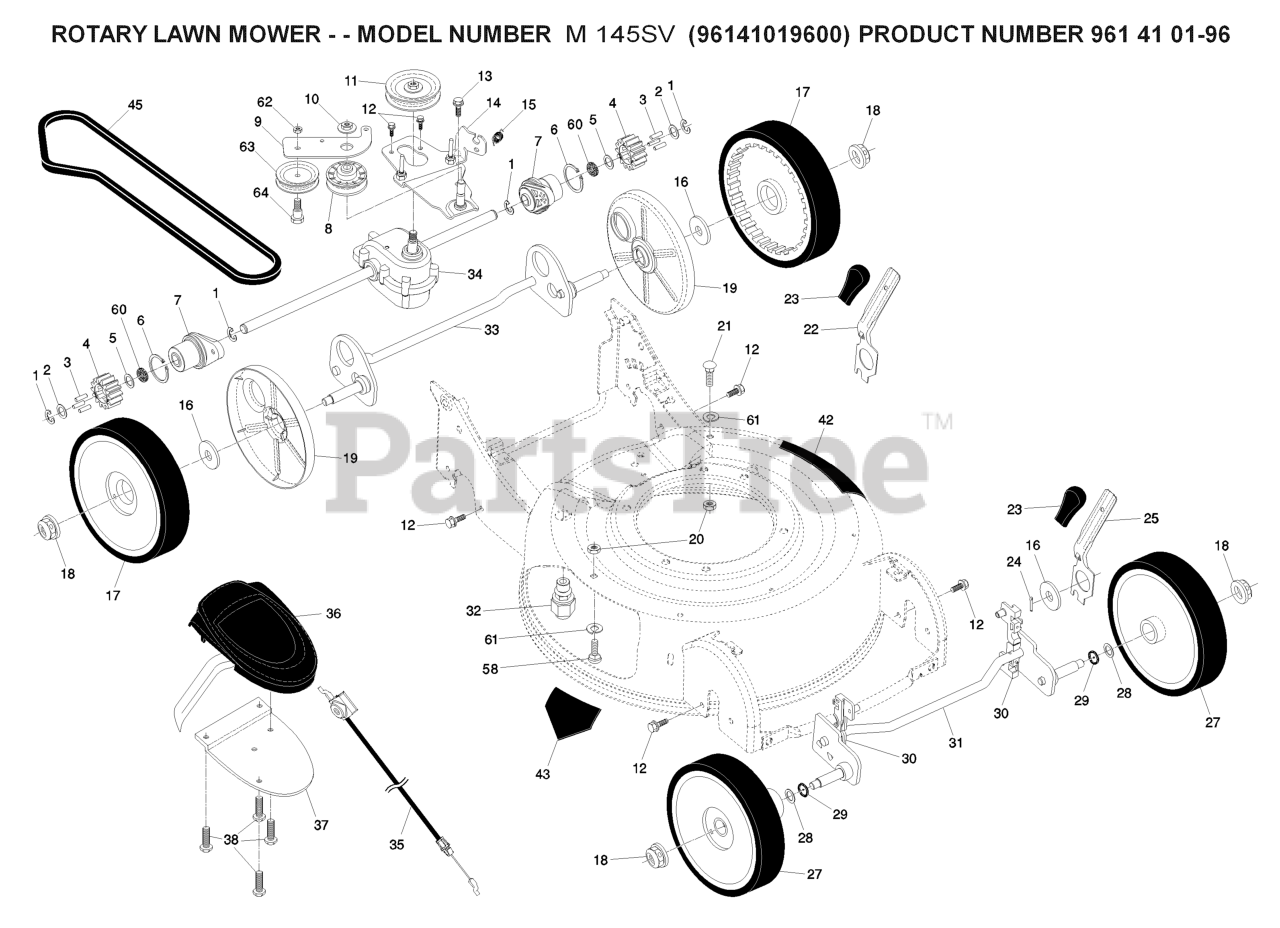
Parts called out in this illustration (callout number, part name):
1	E-RING 7/16 RE
2	THRUST WASHER
3	PAWL.DRIVE.ETCHED
4	PINION.DRIVE.WALK
6	RETAINING RING (2 2)(3 2)
8	PULLEY.IDLER.V-BELT
9	ARM.IDLER.BZP
10	NUT.HEX.FLANGE.3/8-16.LOCKNUT
11	PULLEY.1.PIECE
13	SCREW 14-20 X 5/8
15	SPRING.RETURN
16	WASHER FLUT
17	WHEEL.8X1.75.H3SPK.RAD3.GY.BU3
18	NUT.HEX.FLANGE.3/8-16.LO(3 2)
19	COVER.DUST.WHEEL
20	NUT, HEX
24	SPRING RETAINER
27	WHEEL & TIRES ASSY, FRONT
28	WASHER.FLAT.1/2
29	O-RING..070X.487.NEOPRENE
30	BUSHING.FRONT.TORQUE.S
36	CONTROL.DR.HV.RGD.GRY/BLU.45CM
37	BRACKET.DRIVE.CONTROL.MOUNT.BL
38	SCREW, PHILLIPS HEAD 10 X 5/8
43	DECAL.INTERNATIONL.CUTFINGER
58	BOLT.CARRIAGE.1/4-20 X 7/8
61	LOCKWASHER
62	NUT.CENTERLOCK.5/16-
63	IDLER PULLEY
64	SHOULDER BOLT
